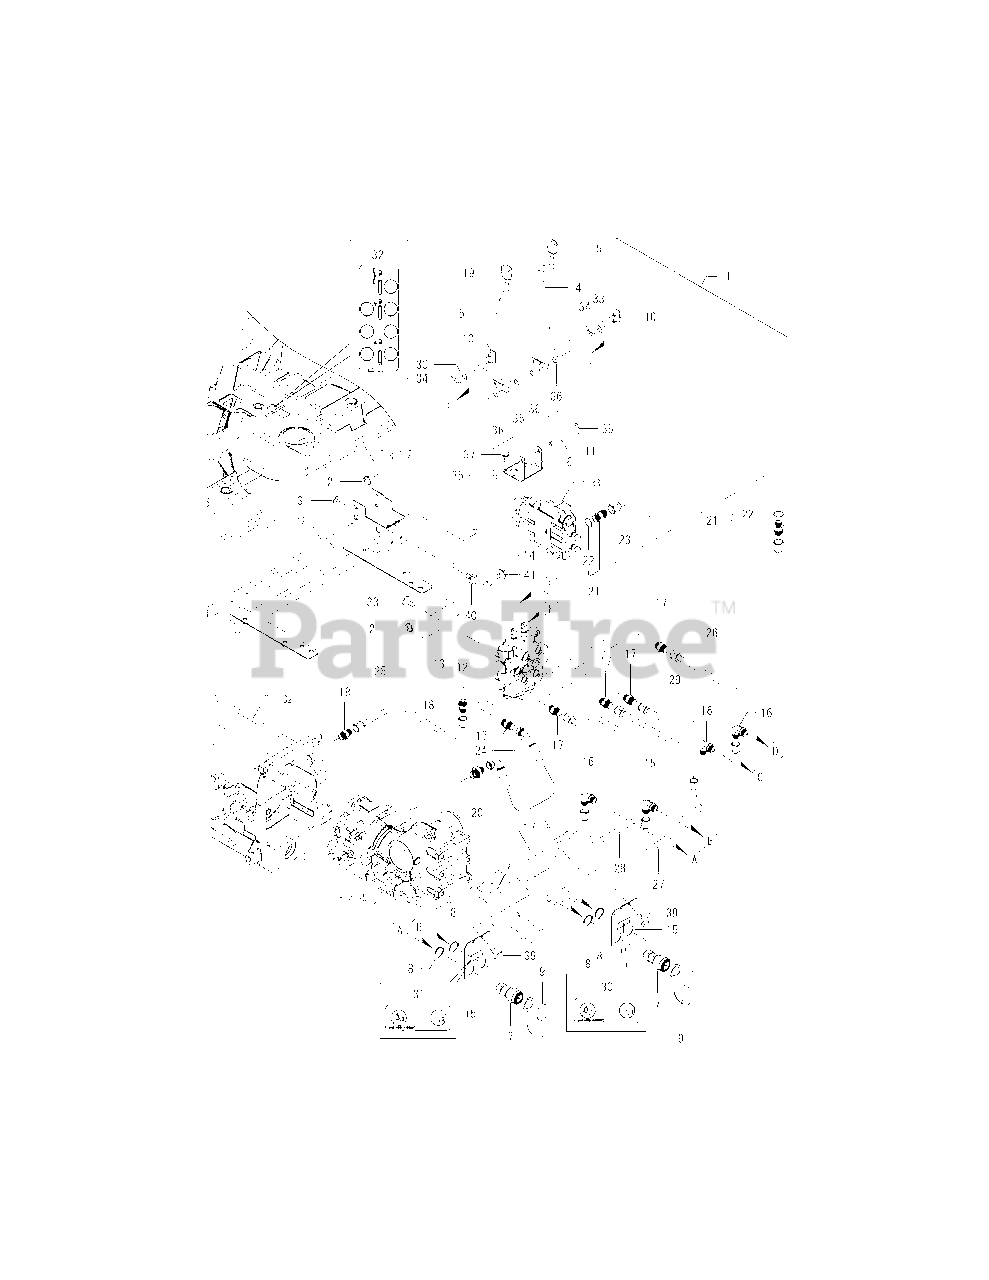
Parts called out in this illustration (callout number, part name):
1	REMOTE KIT, REAR
2	NUT W/WASHER 8
3	NUT W/WASHER 8
6	STAY ASSY, LEVER
7	COUPLER,QUICK 1/2F
13	STAY ASSY, VALVE
20	CONNECTOR UNF8-G1/2
21	FITTING/HYD, 3/4-7/8
30	LABEL, SCV PORT 1
31	LABEL, SCV PORT 2
32	LABEL,R REMOTE LEVE
33	WASHER 8, POLISHED
34	SNAP PIN (JASO 8)
36	BUSH 10X10, DRY
37	BOLT M 6X 16 PLATED
38	BOLT M 8X 12 PLATED
39	BOLT M 8X 16 PLATED
40	BOLT M 8X 20 PLATED
41	BOLT M 8X 20 PLATED
